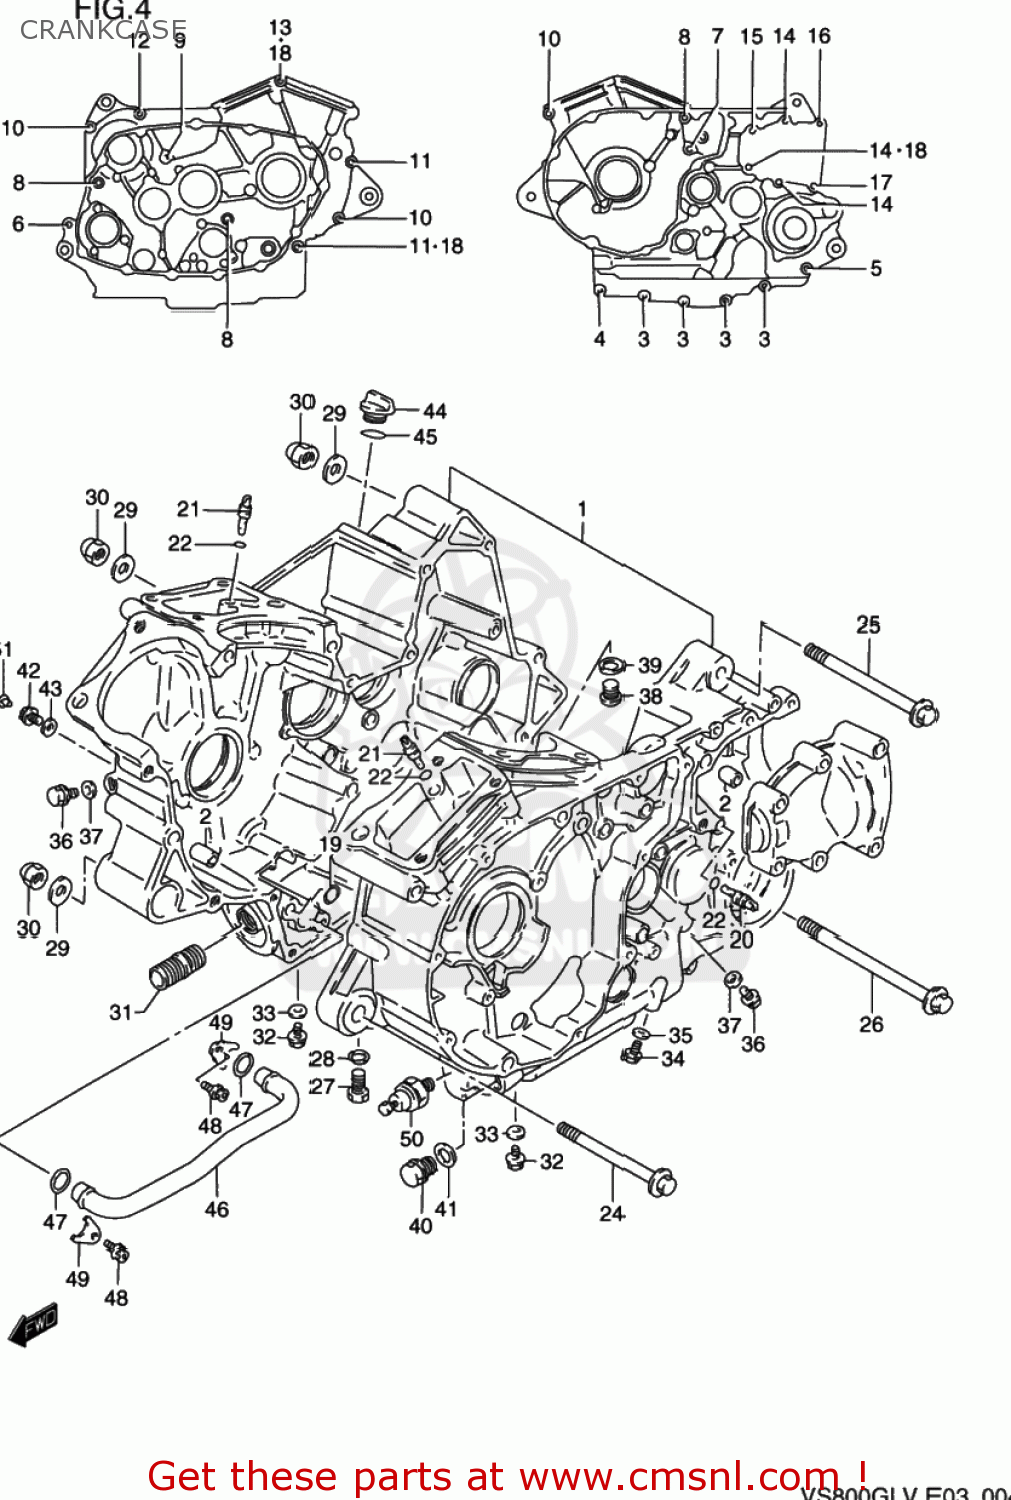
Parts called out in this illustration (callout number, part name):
1	CRANKCASE SET
2	PIN(8.4X11X20)
3	BOLT
4	BOLT
5	BOLT
6	BOLT
7	BOLT
8	BOLT
9	BOLT(8X120)
10	BOLT(8X95)
11	BOLT(8X105)
12	BOLT(8X120)
13	BOLT(8X160)
14	BOLT
15	BOLT
16	BOLT(8X55)
17	BOLT(8X65)
18	GASKET 8.2X14X1 (NAS)
19	O-RING
20	JET,OIL GALLERY
21	JET,AIR(14)
22	O RING(D:1.2,ID:4)
23	WASHER(48.1X64X1.94)
24	BOLT(10X125)
25	BOLT(10X130)
26	BOLT(10X150)
27	BOLT
28	GASKET(12.1X16.2X3.7) (NAS)
29	WASHER
30	NUT
31	UNION,OIL STAND
32	BOLT
33	GASKET(8.2X14X1).6 (NAS)
34	PLUG(10X12)
35	GASKET(10X14X3.6) (NAS)
36	BOLT
37	GASKET(5.8X13X1.2) (NAS)
38	PLUG
39	GASKET(16X22X2) (NAS)
40	PLUG(14X12)
41	GASKET(14X19.2X2) (NAS)
42	BOLT
43	GASKET(8.2X14X1).6 (NAS)
44	PLUG
45	O RING(D:3.1,ID:16.8)
46	PIPE,OIL GALLERY
47	O RING(D:3.1,ID:14.8)
48	BOLT
49	CLAMP,OIL PIPE
50	SWITCH ASSEMBLY
51	CAP(OD:11)
